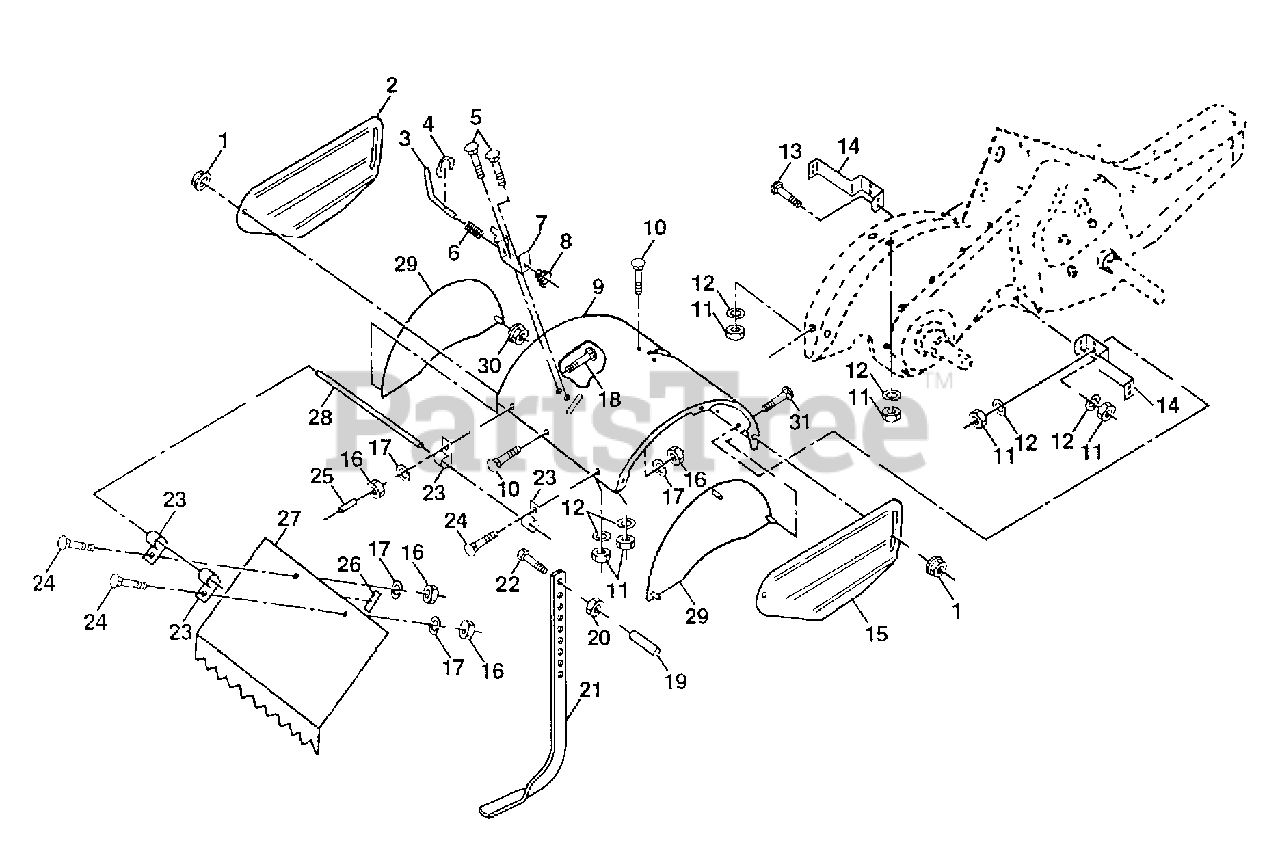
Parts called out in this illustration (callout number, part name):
1	NUT
2	SHIELD.SD.OUT.LH
3	STAKE PIN TI
4	KLIP RING TI
5	BOLT CRT
6	SPRING TI
7	LATCH BRACKET TI
8	SPRING CRT
10	BOLT
11	NUT.HEX.5/16-18
12	LOCKWASHER
13	BOLT
14	"BRACKET,SHIELD"
15	SHIELD.SD.OUT.RH
17	LOCKWASHER
18	BOLT
19	GRIP CRT
20	NUT.HEX.3/8-16UNC
22	BOLT
23	HINGE CRT
24	BOLT
25	VINYL CAP TI
26	PAD IDLER TI
28	PIN HINGE
29	SHLD SIDE
30	LOCKNUT TI
31	BOLT
